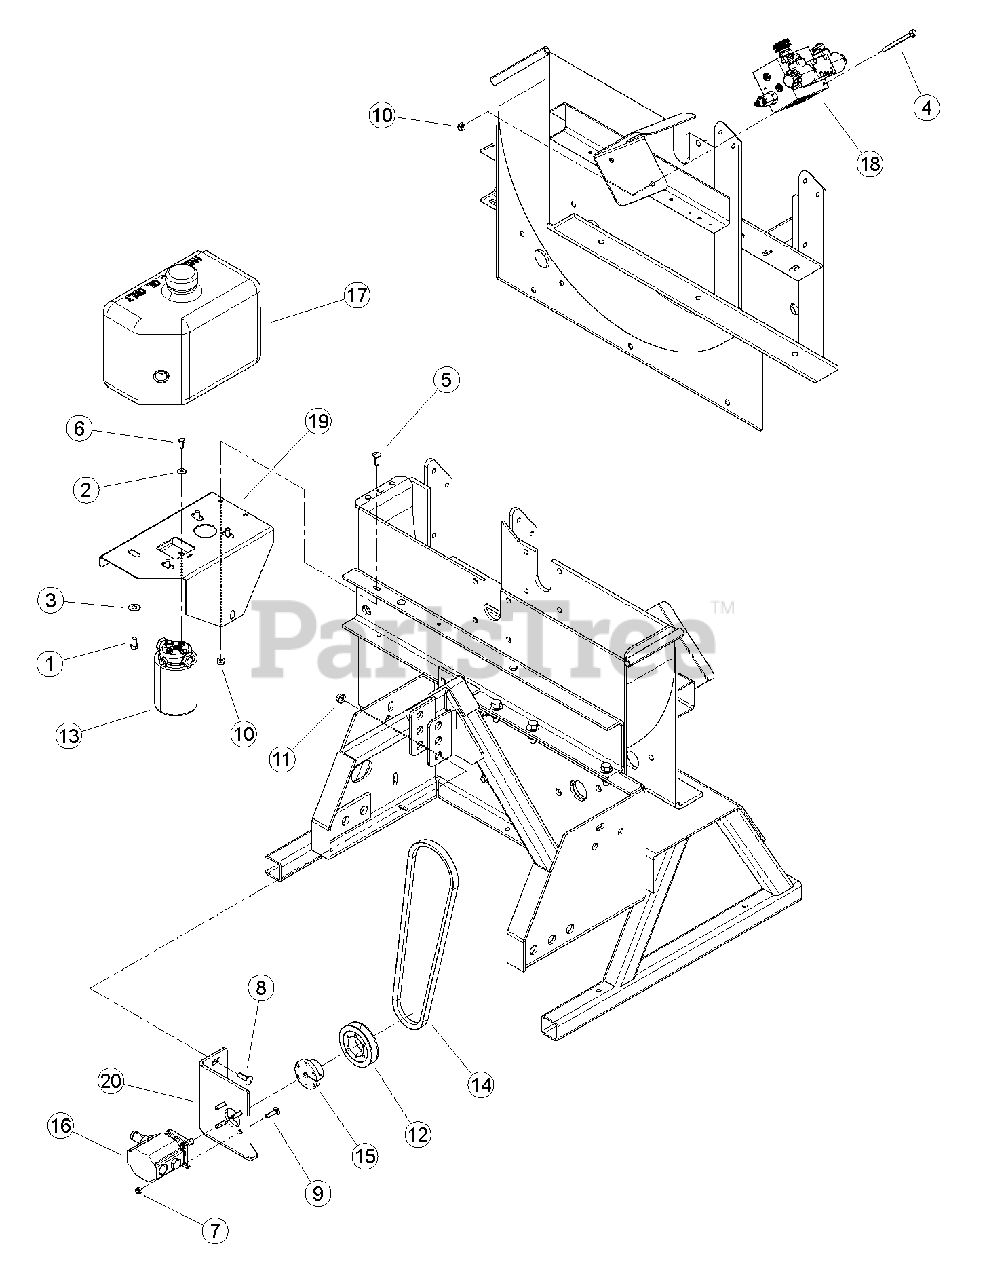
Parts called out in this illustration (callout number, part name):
1	BOLT, 3/8 X 3/4 GR5 HEX CAPSCREW ZP
2	WASHER, 1/4" FLAT ZP
3	WASHER, 3/8" FLAT ZP
4	BOLT, 5/16 X 3-1/2 SERRATED FLANGE NC
5	BOLT, 5/16 X 1" GR5 CRG ZP
6	BOLT, 1/4 X 5/8" HHCS GR5 ZP
7	NUT, 5/16" NE NYLOCK ZP
8	BOLT, 3/8 X 1-1/4" GR5 CRG NC ZP
9	BOLT, 5/16 X 1-1/4" GR5 CRG ZP
10	NUT, 5/16-18 NYLOCK-FLANGE
11	NUT, 3/8-16 NYLOCK FLANGE
12	SHEAVE, 1B3.6 SH
13	ASSEMBLY, HYDRAULIC FILTER
14	BELT, BX44
15	BUSHING, SH 1/2"
16	PUMP, 2 STAGE CW HI/LO 0.605 DISP.
17	TANK, HYDRAULIC
18	ASSEMBLY, HYDRAULIC FEED FLOW VALVE W/ PS
19	WELDMENT, HYDRAULIC TANK BRACKET
20	BRACKET, MOUNT HYDRAULIC PUMP
